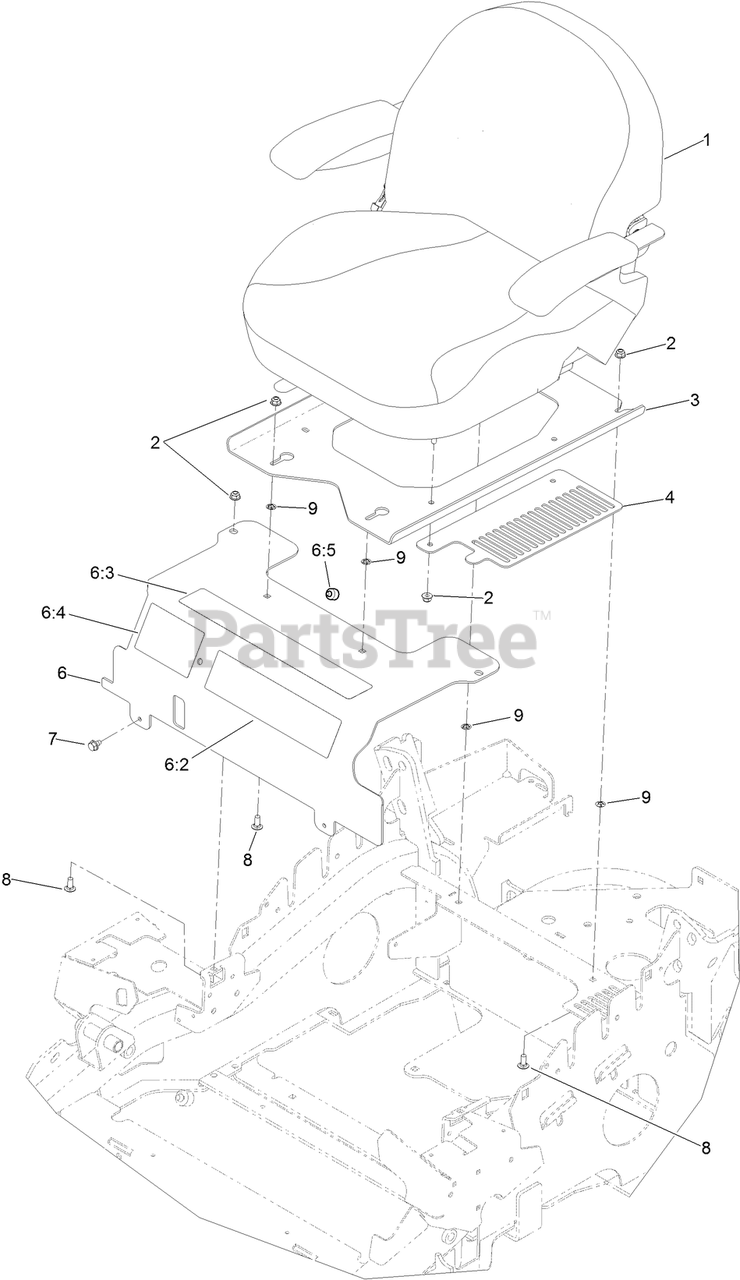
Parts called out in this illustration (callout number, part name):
1	SEAT ASM
2	NUT-HF, NI
3	PLATE-MOUNT, SEAT
4	PLATE-COVER, FAN
6	SEAT MOUNT PANEL ASM
6:3	DECAL-CONSOLE
6:4	DECAL-SERVICE AID
6:5	BUMPER-GROMMET
7	SCREW
8	SCREW-CARR
9	NUT-PUSH
